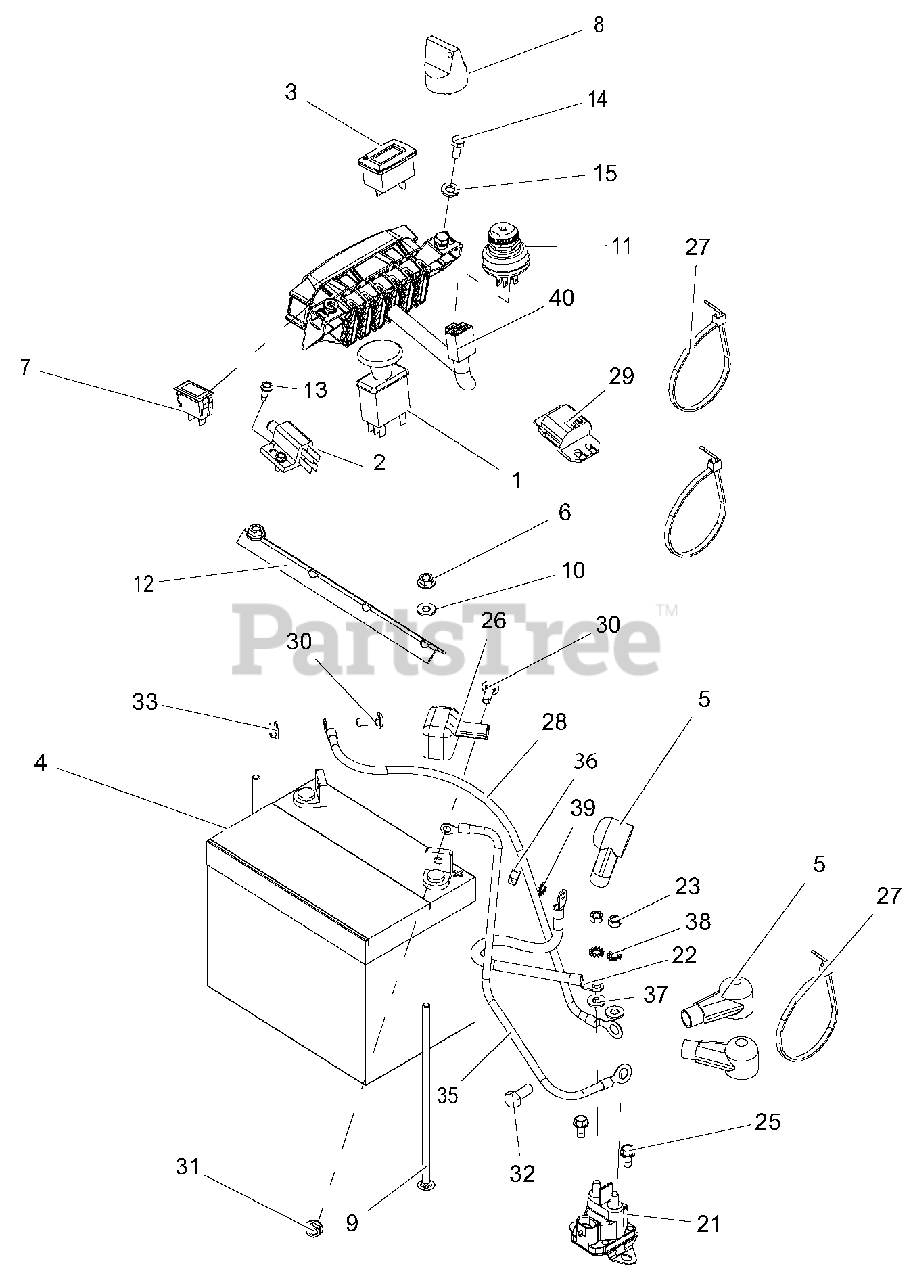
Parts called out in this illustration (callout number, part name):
1	SWITCH, CLUTCH
2	SWITCH- DOUBLE POLE N.O./N.O.
3	METER, HOUR W/MAINTENANCE
4	BATTERY, 12V-U1-CCA270MIN
5	BOOT, BATTERY TERMINAL-RED
6	@NUT-SPNLK-FLG .25-20 YWZC
7	LIGHT, INDICATOR
8	KEY, W/ COVER
9	BLT-RDHDSQNK .25-20X7.50 G2 YWZC
10	WSHR-FL-STL.281X.62X.065 YWZC
11	SWITCH, IGNITION
12	HOLD DOWN - BLK
13	SCR-TAP 10-24X.50 HWH TR YWZC
14	@BLT-HEX M6-1X16 YWZC
15	WSHR-LK .31X.078 REG YWZC
21	SOLENOID, STARTER (SEALED)
22	CABLE, POS W/(2) 1/4 RING 9.0 LG
23	NUT-HEX M6-1.00 YWZC
25	SCR, TAP .25-20X.50
26	INSULATOR
27	CABLE, TIE 5.50 LG
28	CABLE-GROUND .25 X 13.00 X .31 REV A2
29	MODULE, INTERLOCK
30	BLT-RDHDSQNK .25-20X.75 G5 YWZC
31	@NUT-SPNLK-FLG .25-20 YWZC
32	@BLT-HEX M8-1.25X20 YWZC
33	@NUT-SPNLK-FLG .25-20 YWZC
35	CABLE, STARTER 13.00"
36	NUT-LK-CTR .25-20 YWZC
37	WSHR-FL-STL.281X.62X.065 YWZC
38	@, WSHR-LK-EXT.262X.502X.026 YWZC
39	@, WSHR-LK-EXT.262X.502X.026 YWZC
40	HARNESS, PROSTANCE WIRING
